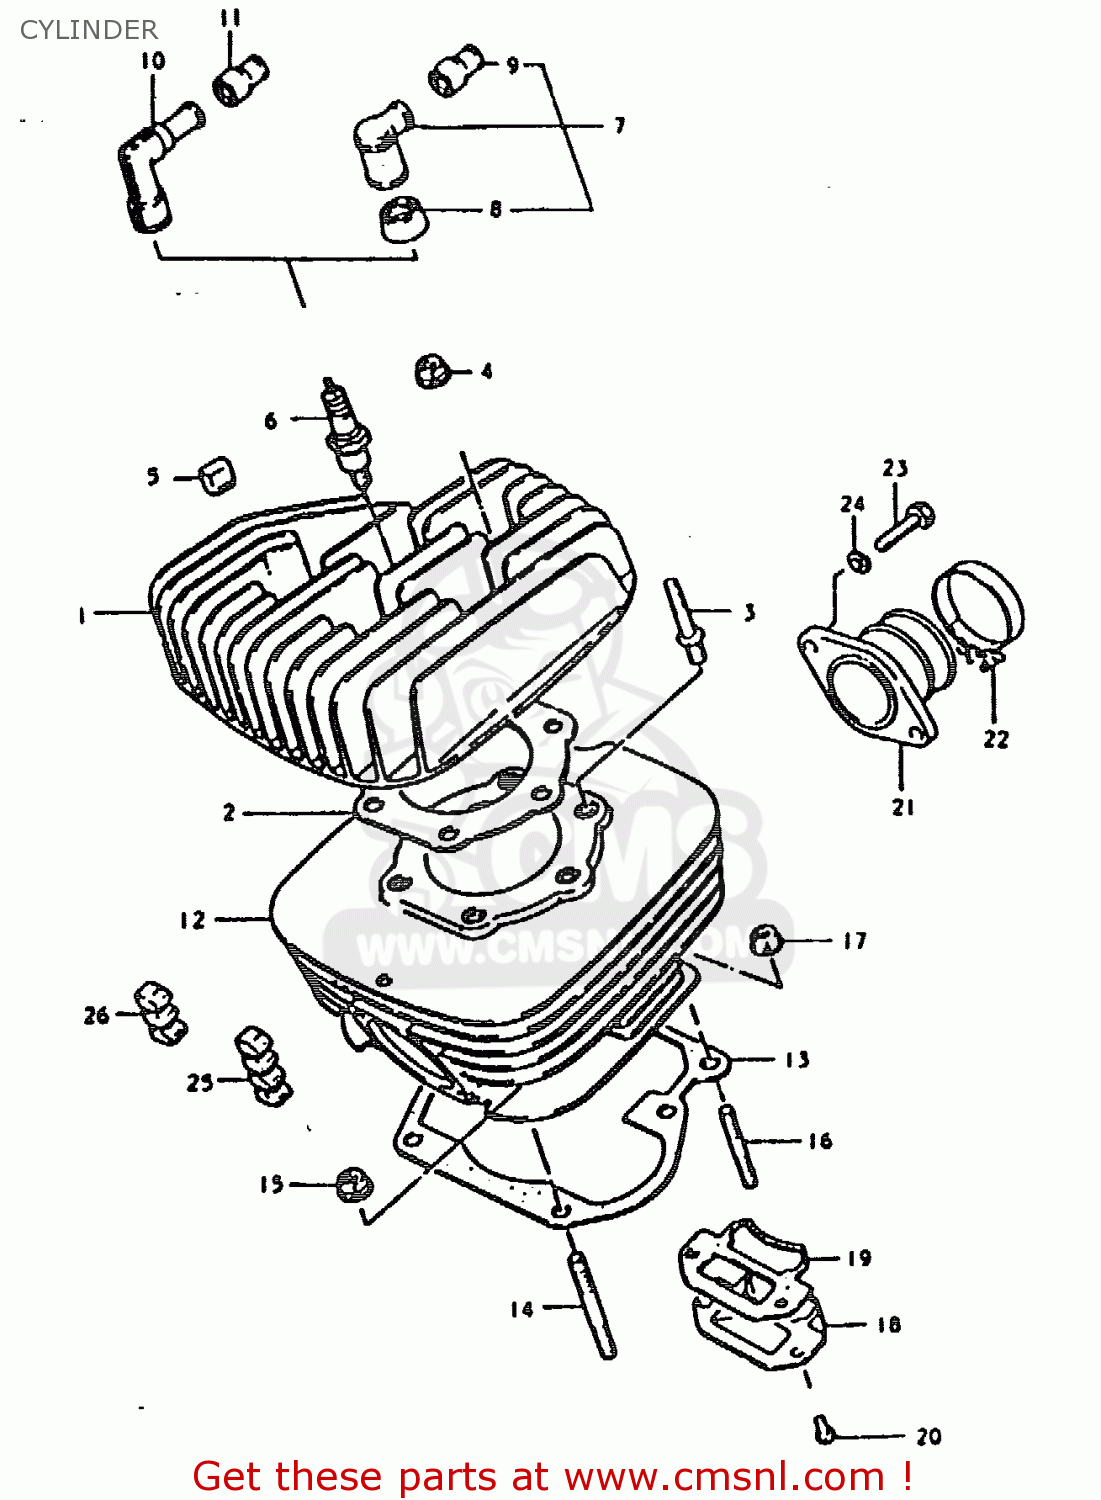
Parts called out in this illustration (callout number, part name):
1	HEAD,CYLINDER
2	GASKET,CYLINDER HEAD (NAS)
3	BOLT,STUD
4	NUT
5	PAD,CYLINDER
6	SPARK PLUG W22EP
10	CAP,SPARK PLUG
11	SEAL,SPARK PLU
12	CYLINDER
13	GASKET,CYLINDER (MCA)
14	STUD 10X25
15	NUT
16	STUD 8X25
17	NUT
18	VALVE ASSY,REED
19	GASKET,REED VALVE (MCA)
20	SCREW
21	PIPE,INTAKE
22	CLAMP
23	BOLT, UPPER
24	LOCK WASHER
25	PAD,CYLINDER
26	PAD,CYLINDER
